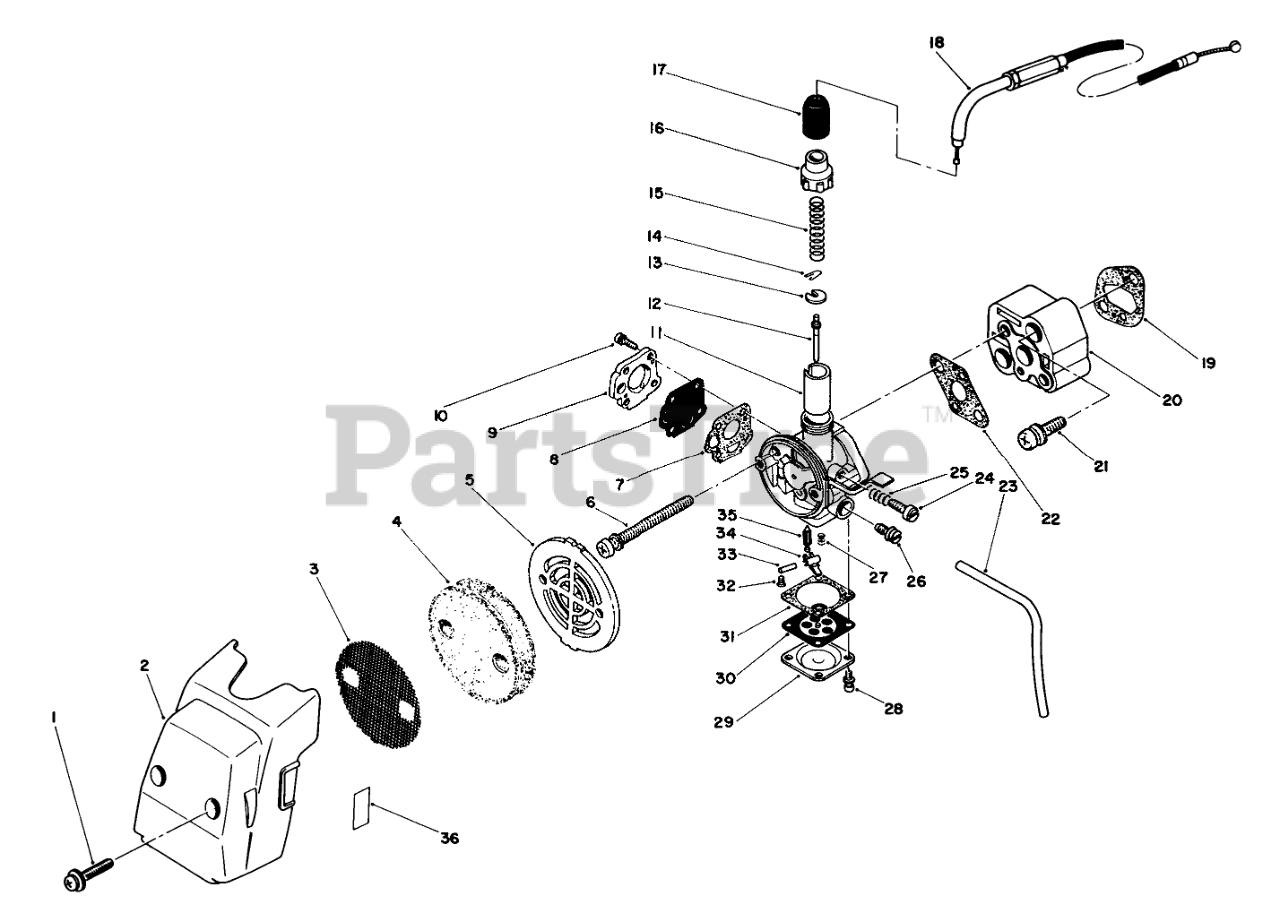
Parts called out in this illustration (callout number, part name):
1	SCREW & WASHER
2	CLEANER CASE
3	SCREEN
4	ELEMENT
6	SCREW W/ WASHER
7	PUMP COVER GASKET
8	PUMP DIAPHRAGM
9	Pump Cover Assembly
10	SCREW W/ WASHER
11	THROTTLE VALVE
12	NEEDLE JET
13	SPRING RETAINER
14	NEEDLE CUP
15	SPRING
17	AIR SEAL
18	THROTTLE WIRE
19	INSULATOR GASKET
20	INSULATOR
21	SCREW & WASHER
22	CARB GASKET
23	FUEL TUBE
24	Screw-Adjusting
25	ADJ. SCREW SPRING
26	Needle-Main Jet
27	VALVE SPRING
28	SCREW W/ WASHER
29	DIAPHRAGM COVER
30	MAIN DIAPHRAGM
31	DIAPHRAGM GASKET
32	FLOAT SCREW
33	FLOAT PIN
34	FLOAT ARM
35	FLOAT VALVE
36	CHOKE LABEL
